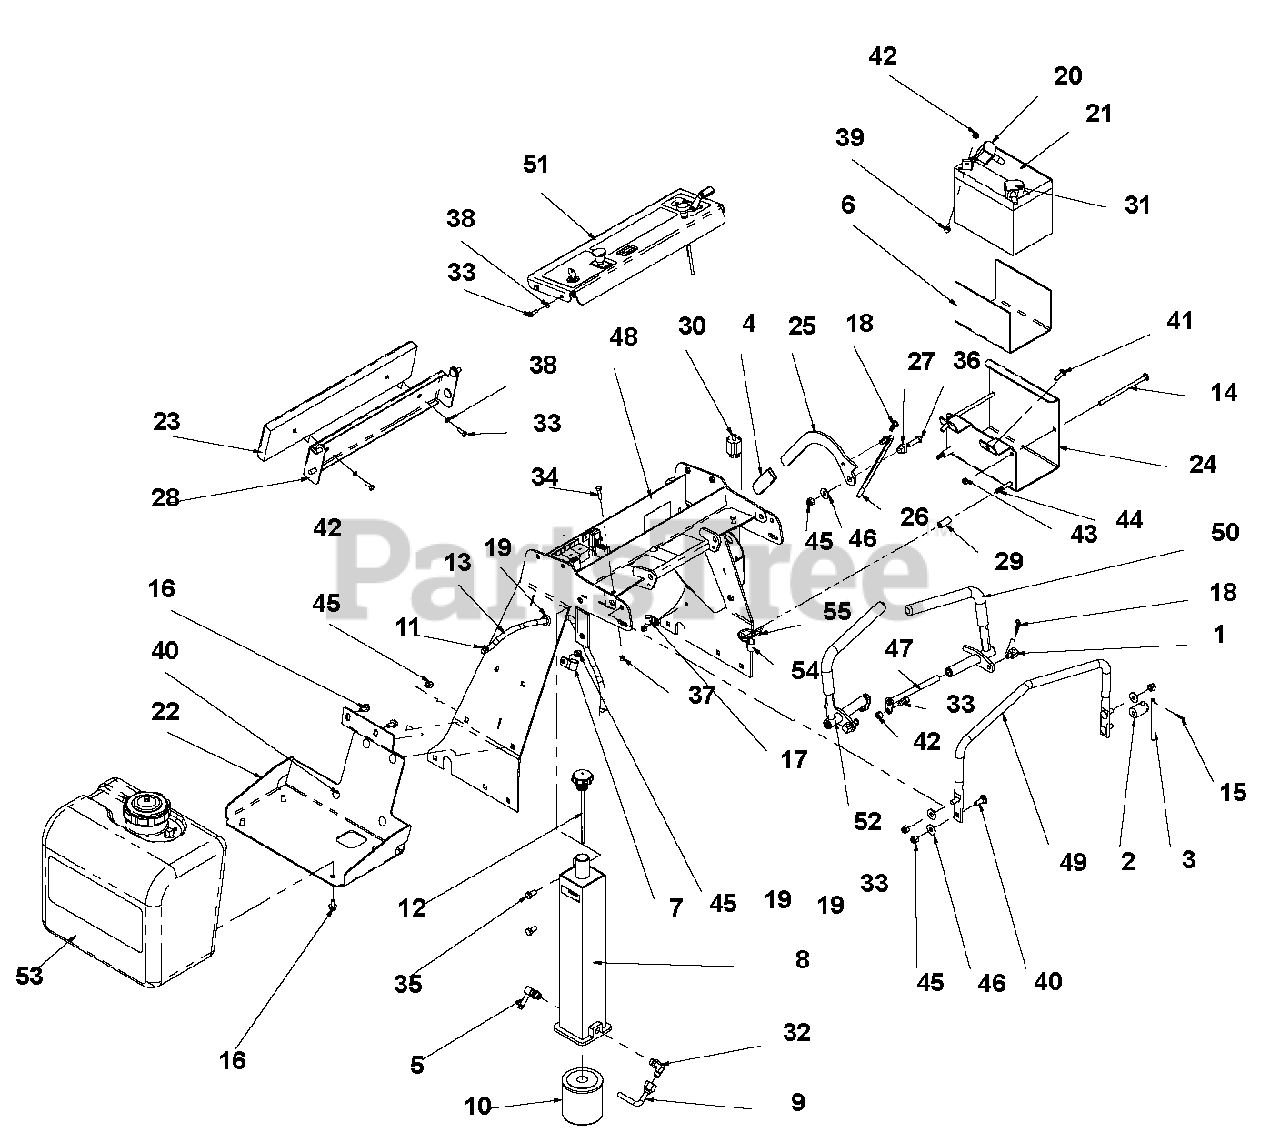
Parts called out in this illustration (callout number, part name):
1	Swivel Adjuster
2	Base, Lock Lever Y
3	Lever, Lock Y
4	Grip, PVC .250 x 1.00 x 3.63
5	Fitting, 90 9/16 MOR x 3/8 Hose
6	Strip, Battery Insulator
7	P-Clip, .750 Insulated
8	Reservoir, Hydraulic S/O
9	Elbow, Fitting
10	Filter, Oil
11	Clamp, Fuel Line
12	Cap, Filler Oil
13	Hose, .25 Low-PERM Bulk Gas
14	Bolt, 5/16-18 x 6.00 CRG 2 Y
15	Pin, Spring
16	Screw, Hex, FL,JDS123, M8 x 1.25 x 16
17	P-Clip, .500 Insulated
18	Pin, Hair .091 x 1.63 5/16-1/2 Y
19	Grommet, Round Rubber .625 x .19
20	Cable, Battery Starter - 48"
21	Battery, 12V-U1-CCA270 Min
22	Bracket, Fuel Tank Mounting
23	Pad, Thigh
24	Tray, Battery
25	Lever, Brake
26	Link. Brake Y
27	Bushing, Brake Pivot Y
28	Weldment, Thigh Pad Bracket
29	Bushing, .364 x .540 x 1.250 Y
30	Switch, NO-NO-NC Grey Plunger
31	Cable, Battery Ground 25"
32	Fitting, 90 9/16 MOR x 9/16 MJIC
33	Bolt, Hex .25-20 x .75 Grade 5
34	Bolt, Hex .25-20 x 1.00 Grade 5
35	Bolt, Hex .38-16 x .75 Grade 5
36	Bolt, Hex .38-16 x 1.25 Grade 5
37	Nut, Hex .25-20
38	Washer, .250 Med. Spring Lock Y
39	Bolt, 1/4-20 x .625 WSH Y
40	Bolt, 3/8-16 x 1.00 CRG 5 SN Y
41	Bolt, 5/16-18 x 1.00 CRG 2 Y
42	Locknut, 1/4-20 Whiz Y
43	Locknut, 5/16-18 Nyloc Y
44	Bolt, 5/16-18 x 2.00 Round Head Square Neck 5 Y
45	Locknut, 3/8-16 Nyloc Y
46	Washer, .375 REG Flat Y
47	Weldment, Pin and Lock
48	Gravely Console With Decals
49	Handle, Support
50	LH Control Lever W/Grip
51	Assembly, Control Panel w/Decals (switches sold separately)
52	RH Control Lever W/Grip
53	Tank, Assy EPA Fuel Gravely
54	P-Clip, .50 Insulated
55	Cable Tie .15 x 8.50
